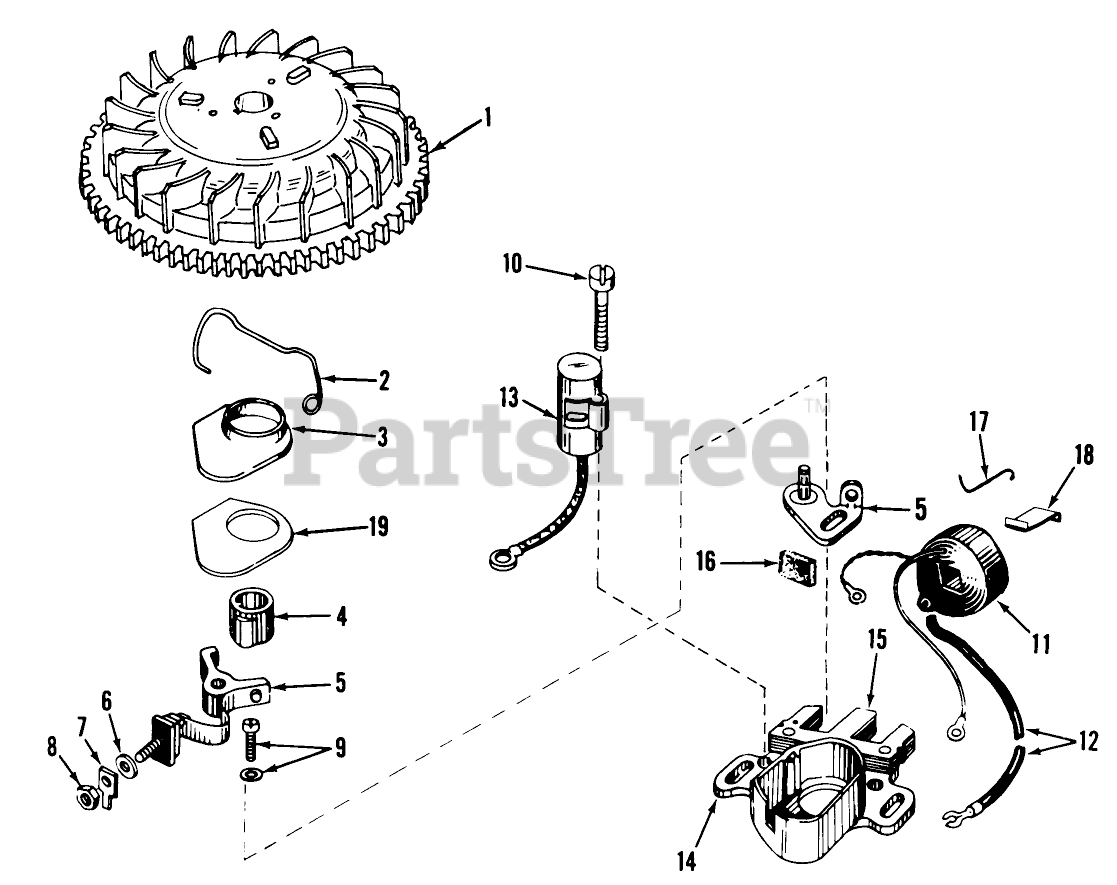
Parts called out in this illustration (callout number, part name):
1	FIywheel
2	Spring Breaker Box
3	Cover, Dust
4	Cam, Breaker
5	Breaker Assy.
6	Washer
7	Terminal
8	DECAL
9	Breaker Screw
10	Condenser Screw
11	Coil Assy., (Inc. Ref. Nos. 12, 13 18)
12	Wire, Lead
13	Condenser
14	Core Plate
15	Stator Assy., (Incl. Nos. 2, 3, 5 thru 14 16 thru 19)
16	Felt,Cam Wiper
17	Clip, Coil
18	Spring Coil Wedge
19	Gasket Dust Cover
